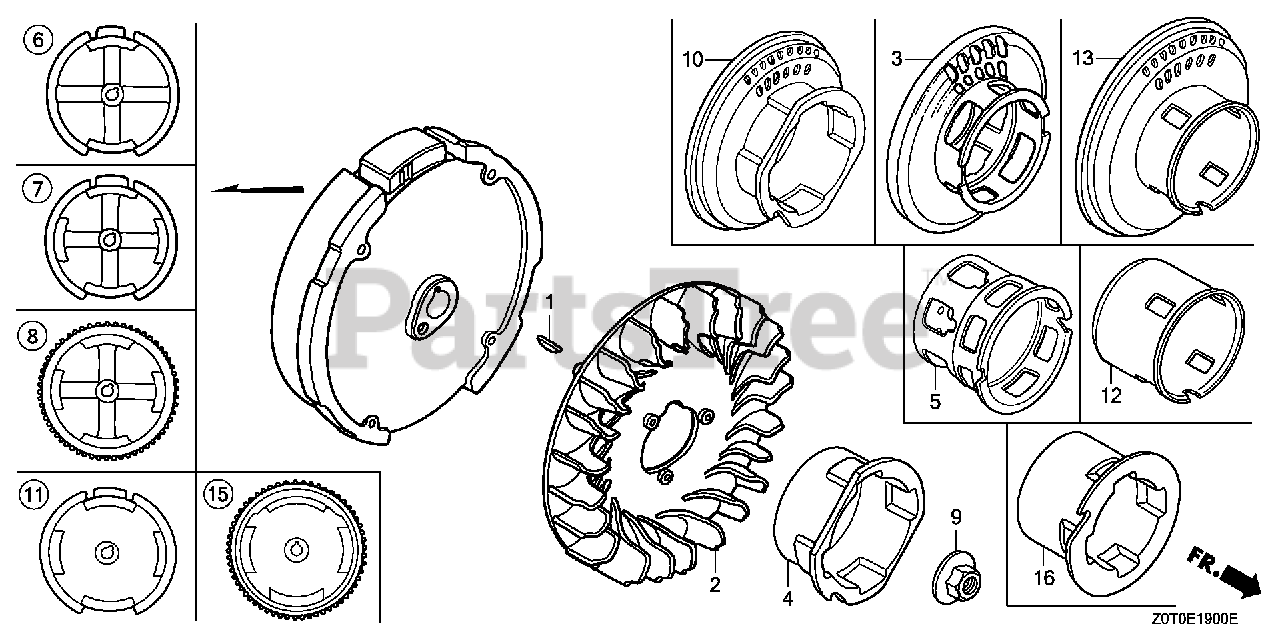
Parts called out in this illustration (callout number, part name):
1	KEY, SPECIAL WOODRUFF (25X18)
2	FAN, COOLING
9	NUT, SPECIAL (14MM)
16	PULLEY, STARTER
